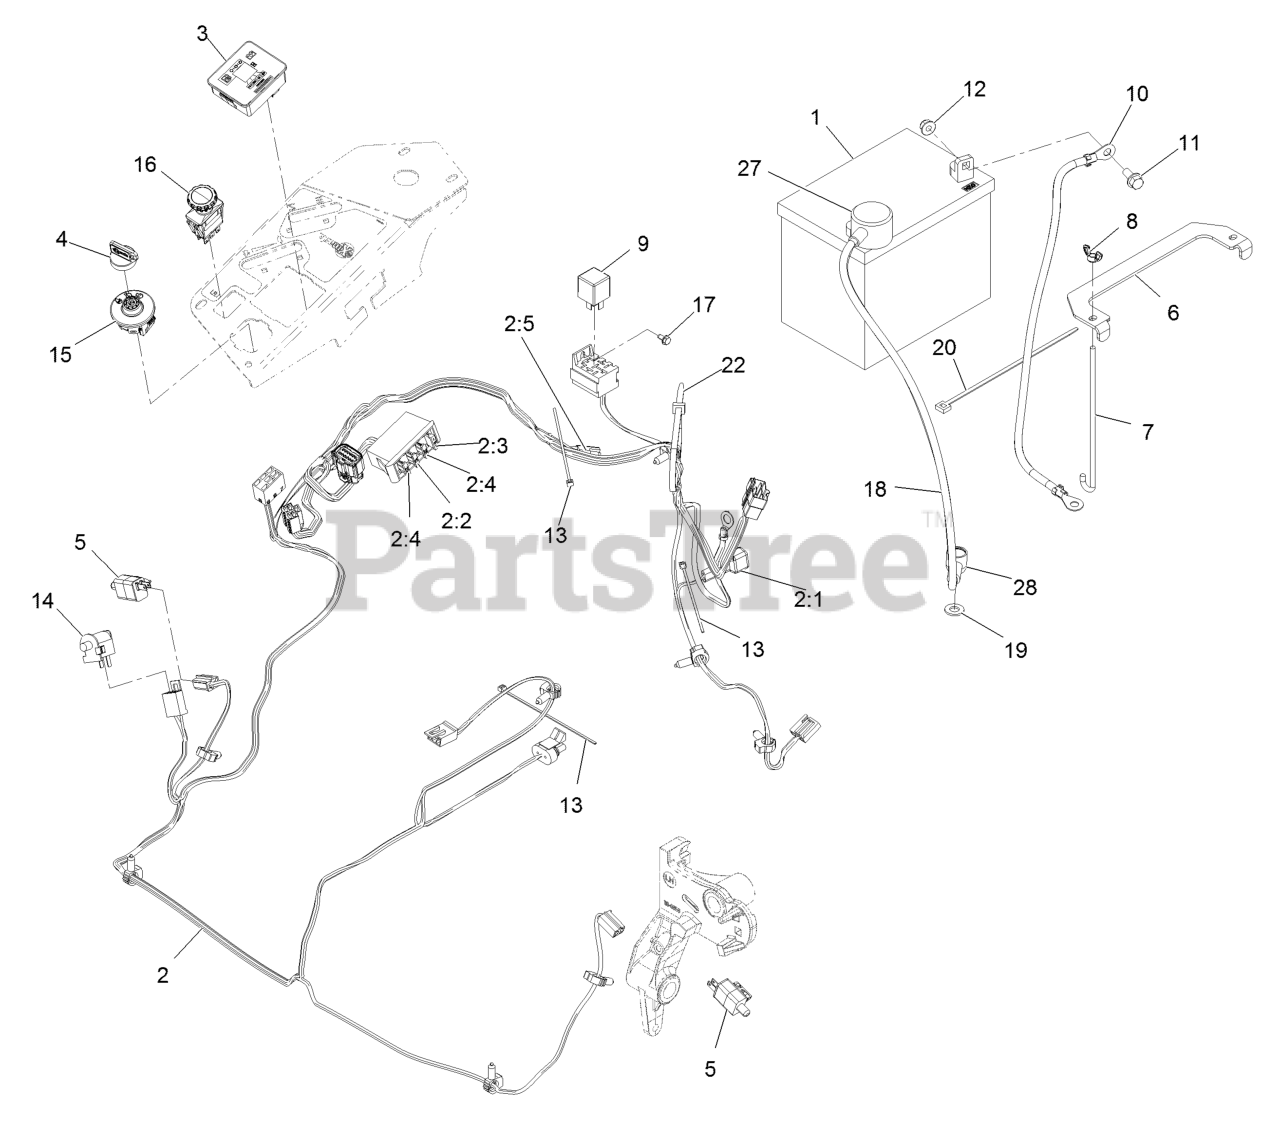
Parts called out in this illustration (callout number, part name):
1	Battery (300 Cca, Wet)
2	HARNESS-WIRE, MAIN
2:2	FUSE-BLADE, 10 AMP
2:3	FUSE-BLADE, 15 AMP
2:4	FUSE-BLADE, 25 AMP
2:5	CAP-PLUG
3	FUEL/HOUR METER ASM
4	KEY-IGNITION
6	STRAP-TIE DOWN, BATTERY
7	BOLT-HOLDDOWN
8	WINGNUT
10	CABLE-BATTERY, NEGATIVE
11	SCREW-HHF
12	NUT-HF, NI
13	TIE-CABLE
14	SWITCH-BAIL
16	SWITCH-PTO, 10 AMP
17	SCREW-HWH
18	CABLE-BATTERY, POSITIVE
19	WASHER-FLAT
20	TIE-PLASTIC
22	TIE-PLASTIC
27	INSULATOR-BATTERY
28	INSULATOR-SOLENOID
